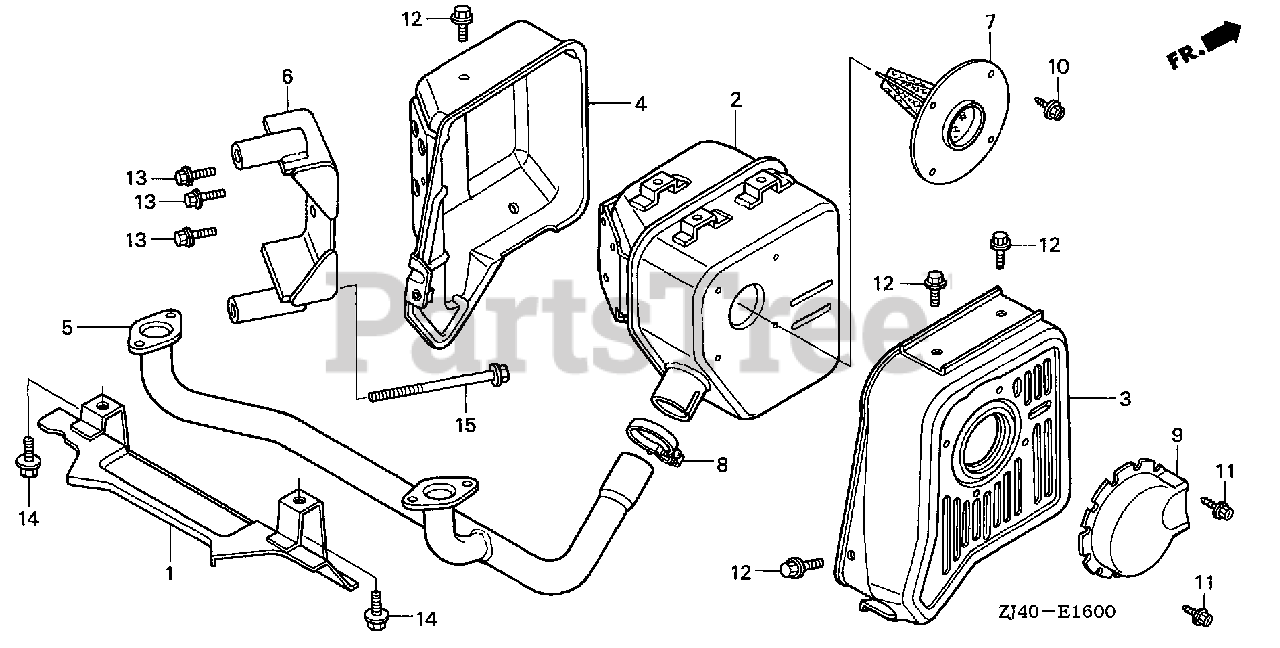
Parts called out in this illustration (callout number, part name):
1	PROTECTOR, EX. PIPE
3	PROTECTOR, MUFFLER (SIDE-L)
4	PROTECTOR, RR. MUFFLER
6	STAY, MUFFLER
7	ARRESTER, SPARK
8	BAND ASSY.
9	DEFLECTOR KIT, EX.
10	SCREW (NELSON)
11	SCREW, TAPPING (4X8)
12	BOLT, FLANGE (6X8)
13	BOLT, FLANGE (6X12)
14	BOLT, FLANGE (8X16)
15	BOLT, FLANGE (8X80)
